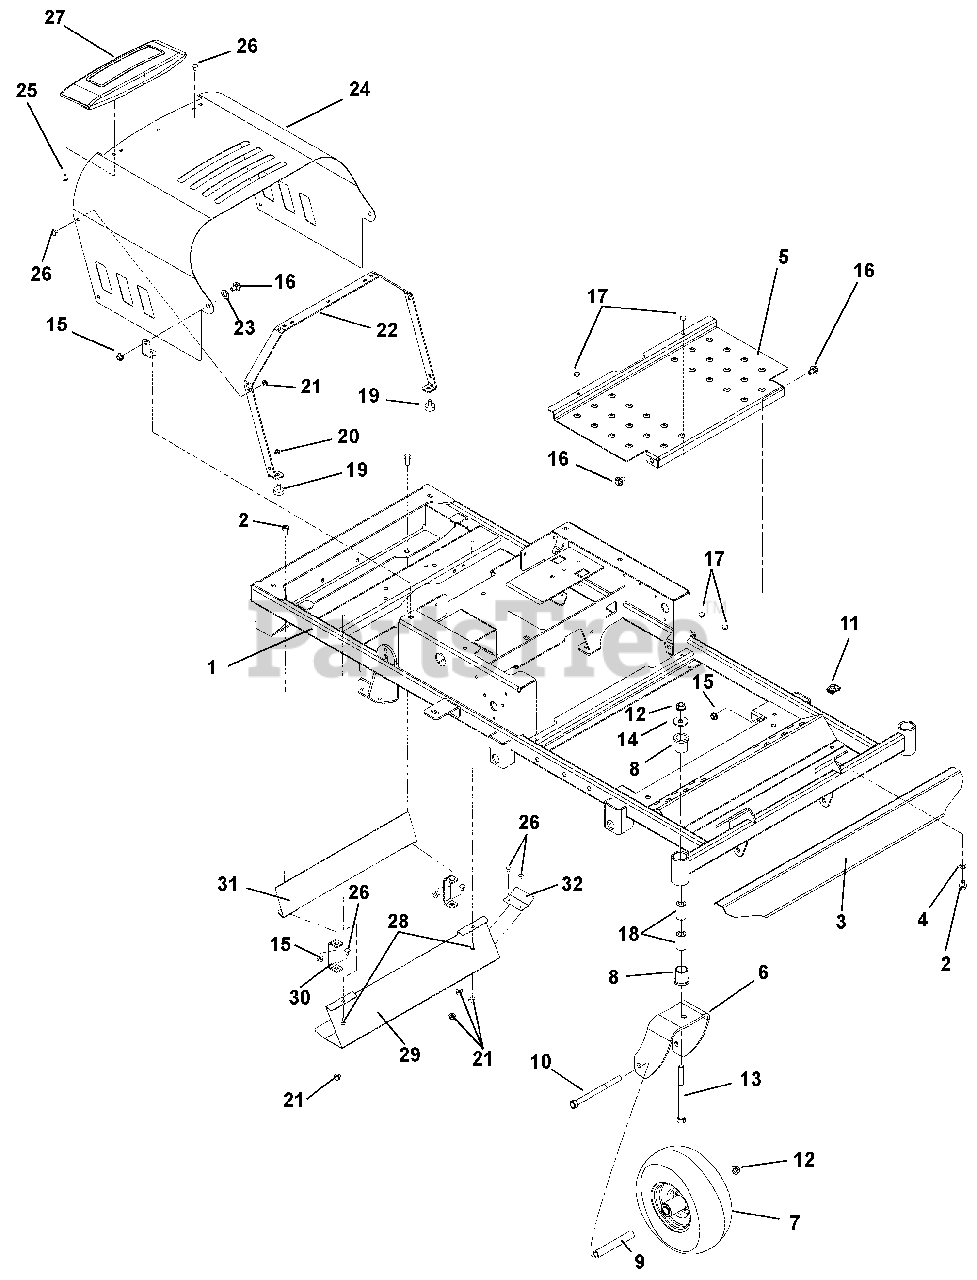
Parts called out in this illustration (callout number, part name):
1	WLDMT, FRAME ZT/ZOOMXL (2013)
2	@BLT-HEX .38-16X1.00 GR5 YWZC
3	WMT, FOOTREST
4	@WSHR-LK .38X.094 REG YWZC
5	DECK ACCESS PANEL
6	WMT, CASTER FORK
7	TIRE/WHEEL ASSY, 11X4-5
8	BSHG-FLG 1.00X1.25X1.50X1.50
9	SPACER, ROLLED WHEEL
10	@BLT-HEX .50-13X6.50 GR5 YWZC
11	NUT-RTNR .375-16X.37
12	@NUT-LK-TOP-FLG .50-13 YWZC
13	@BLT-HEX .50-13X5.00 GR5 YWZC
14	WSHR-FL-STL.511X1.441X.125 YWZ
15	@NUT-LK-TOP-FLG .38-16 YWZC
16	BOLT-SHLDR .375-16X.150
17	BUMPER GROMMET
18	SPACER, CASTER .50X1.00X1.84
19	BUMPER, RUBBER
20	@NUT-SPNLK-FLG .312-18 YWZC
21	@NUT-LK-TOP-FLG .25-20 YWZC
22	HOOD STRAP
23	WSHR-FL-NYL .518X1.000X.080
24	HOOD, XL
25	SCR-HEX .25X14-.75
26	@BLT-RDHDSQNK .25-20X.50 G5YZ
27	TRIM-ZOOM XL HOOD ARIENS
28	SCR-TAP .25-20X.50 HWH TR YWZ
29	GUARD, MUFFLER HEAT
30	STRAP, MUFFLER GUARD
31	SHIELD, HOT SURFACE
32	DEFLECTOR, HEAT SHIELD
